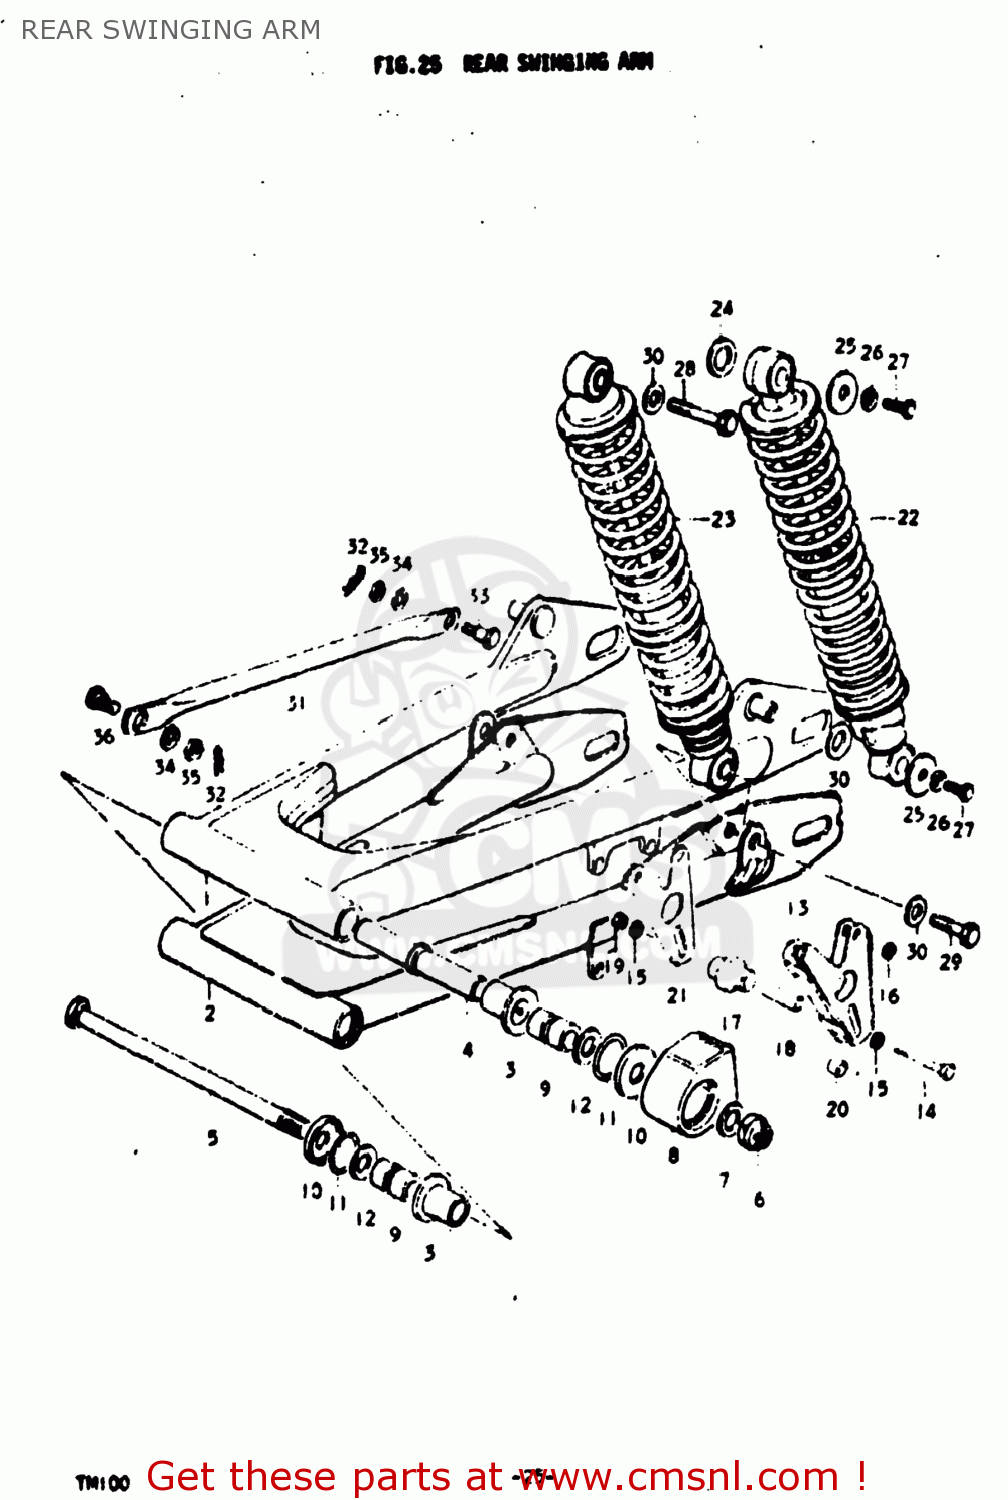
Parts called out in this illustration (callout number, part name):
1	SWING ARM ASSEMBLY,REAR
2	SWING ARM ASSEMBLY,REAR
3	BUSHING
4	SPACER,SWING ARM,CENTER
5	SHAFT,REAR SWING ARM
6	NUT
7	WASHER
8	BUFFER,CHAIN TOUCH DEFENSE
9	SPACER,RR SWGARM PIVOT
10	COVER,SWGARM BUSH DUST SEAL
11	O RING(D:2,ID:24.5)
12	WASHER(12.5X24X2.3)
14	BOLT
15	WASHER
16	LOCK WASHER
17	ROLLER,CHAIN GUIDE
18	SPACER
19	NUT
20	SPACER(6.5X12X6.9)
21	TENSIONER,CHAIN
22	ABSORBER ASSEMBLY,REAR SHOCK
23	ABSORBER ASSEMBLY,REAR SHOCK
24	WASHER
25	WASHER (6.5X24X1.6)
26	LOCK WASHER
27	BOLT
28	BOLT 12X50
29	BOLT(12X33)
30	WASHER
31	TORQUE LINK,REAR
32	CLIP
33	BOLT(8X26.5)
34	LOCK WASHER
35	NUT
36	BOLT(8X22)
